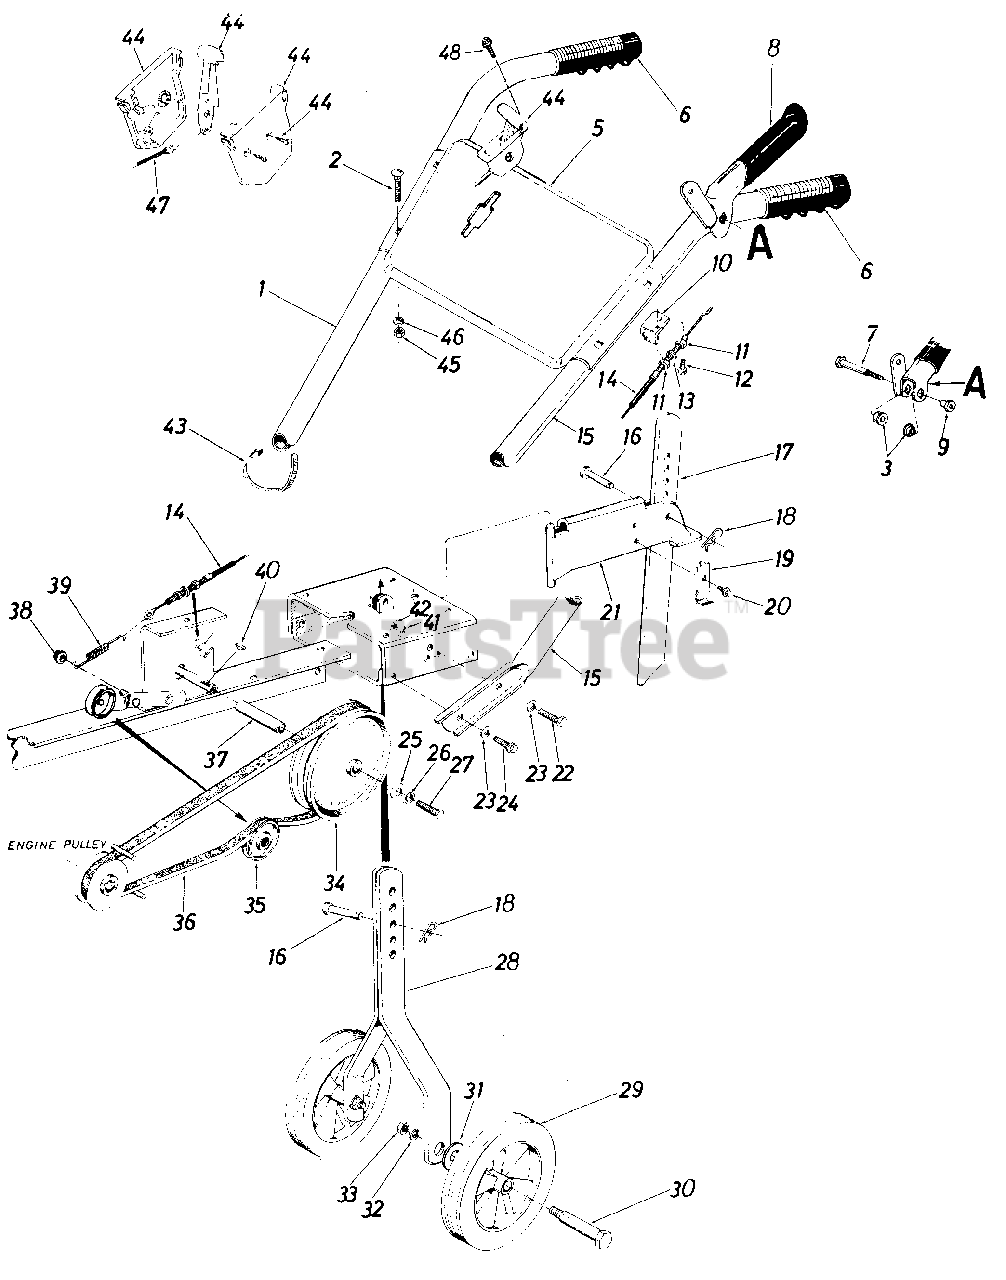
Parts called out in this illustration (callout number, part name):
1	Handle-R.H.
2	Carriage Bolt 5/16-18 x 1.75" Lg.
3	Hex Flange Plastic Brg.
5	Handle Panel
6	Grip
7	Shld. Bolt .38" Dia. x 1.53" Lg.
8	Clutch Grip Ass'y.
9	Shld. Nut 1/4-20 Thd.
10	Cable Support Brkt.
11	Hex Jam Nut 5/16-24 Thd.
12	Hex Wash. Hd. Self-Tap Scr. 1/4-20 x .50" Lg.
13	L-Wash. 5/16" I.D.
14	Clutch Control Cable
15	Handle-L.H.
16	Clevis Pin
17	Depth Bar
18	Hairpin Cotter
19	Depth Bar Spring
20	Hex Wash. Hd. Self-Tap Scr. 1/4-20 x .50" Lg.
21	Tailpiece Ass'y.
22	Hex Scr. 3/8-16 x 1.00" Lg.
23	Belleville Wash. 3/8" I.D.
24	Hex Wash. Hd. Self-Tap Scr. 318-24 x 718" Lg.
25	Fl-Wash. .25" I.D. x .930" O.D. x .120" Thk.
26	L-Wash. 1/4" I.D.
27	Hex Scr. 1/4-28 x .75" Lg.
28	Wheel Bracket Ass'y.
29	Wheel Ass'y. 9 x 1.75
30	Shld. Bolt
31	Belleville Washer 1/2" I.D.
32	L-Wash. 1/2" I.D.
33	Hex Nut 1/2-20 Thd.
34	Pulley 6.00" O.D.
35	Idler Pulley
36	V-Belt 1/2" Pitch x 39"
37	Spacer
38	Cap Speed Nut
39	Extension Spring
40	Hi-Pro Key
41	L-Wash. 3/8" I.D.
42	Hex L-Nut 3/8-16 Thd.
43	Cable Ties
44	Throttle Control Box
45	Hex Nut 5/16-18 Thd.
46	L-Wash. 5/16" I.D.
47	Throttle Control Wire-35"
48	Self-Tap Scr. #10 x 1/2" Lg.
